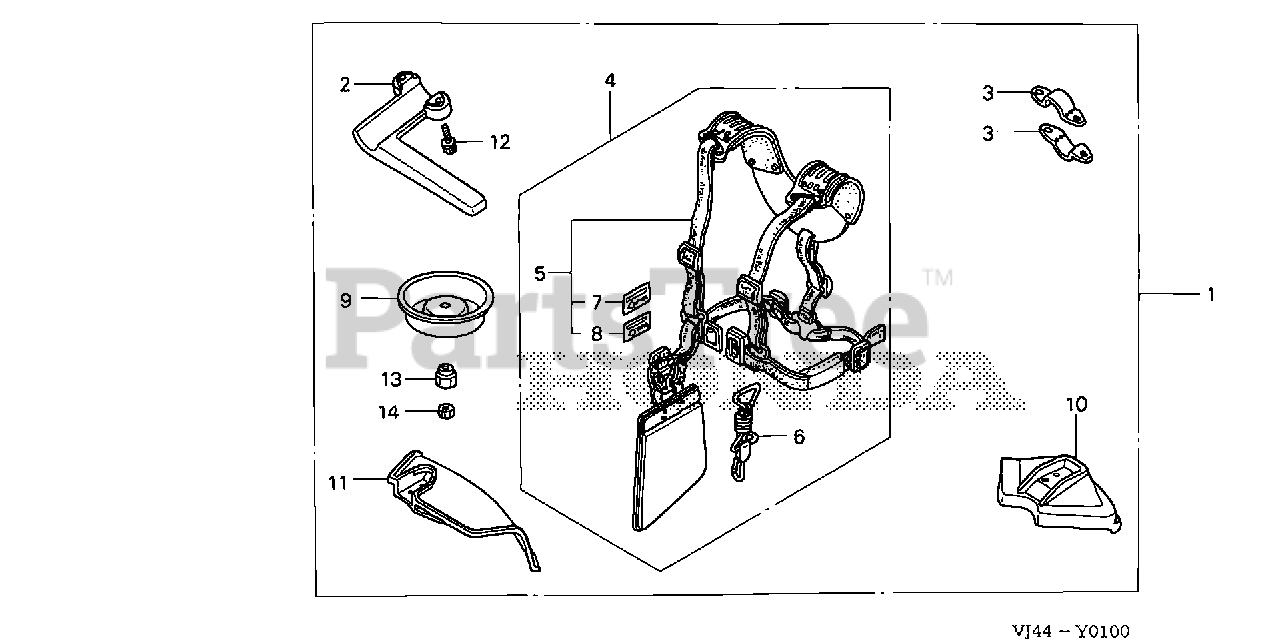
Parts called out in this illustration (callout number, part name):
1	BARRIER KIT
2	BAR, LOOP HANDLE
3	HOLDER, LOOP HANDLE
4	BELT ASSY., SHOULDER
5	BELT, SHOULDER
6	HOOK, SHOULDER BELT
7	MARK, QUICK RELEASE (E)
8	MARK, QUICK RELEASE (F)
9	COVER, NUT
10	DEFLECTOR, GRASS
11	DEFLECTOR, GRASS
12	BOLT, SOCKET (6X18)
13	NUT, LOCK (10MM)
14	NUT, HEX. (6MM)
